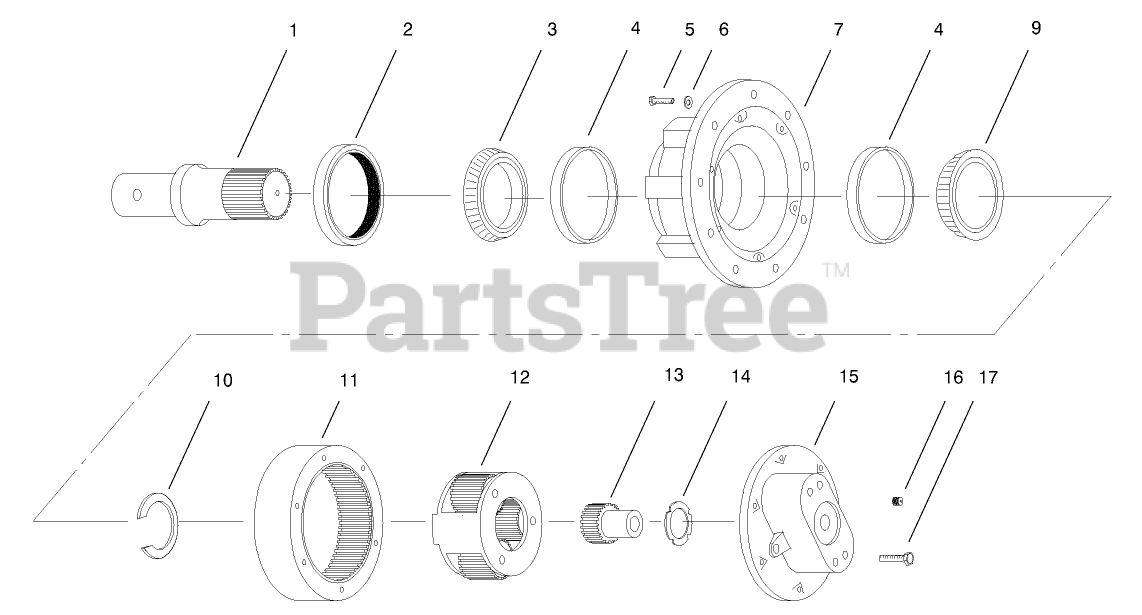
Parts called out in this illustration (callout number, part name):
1	SHAFT - OUTPUT
6	WASHER
7	HUB W/HOLES
10	RETAINING RING KIT
11	GEAR - RING
12	CARRIER ASM
13	GEAR - SUN
14	WASHER
15	COVER
16	PLUG - PIPE, MAGNETIC
